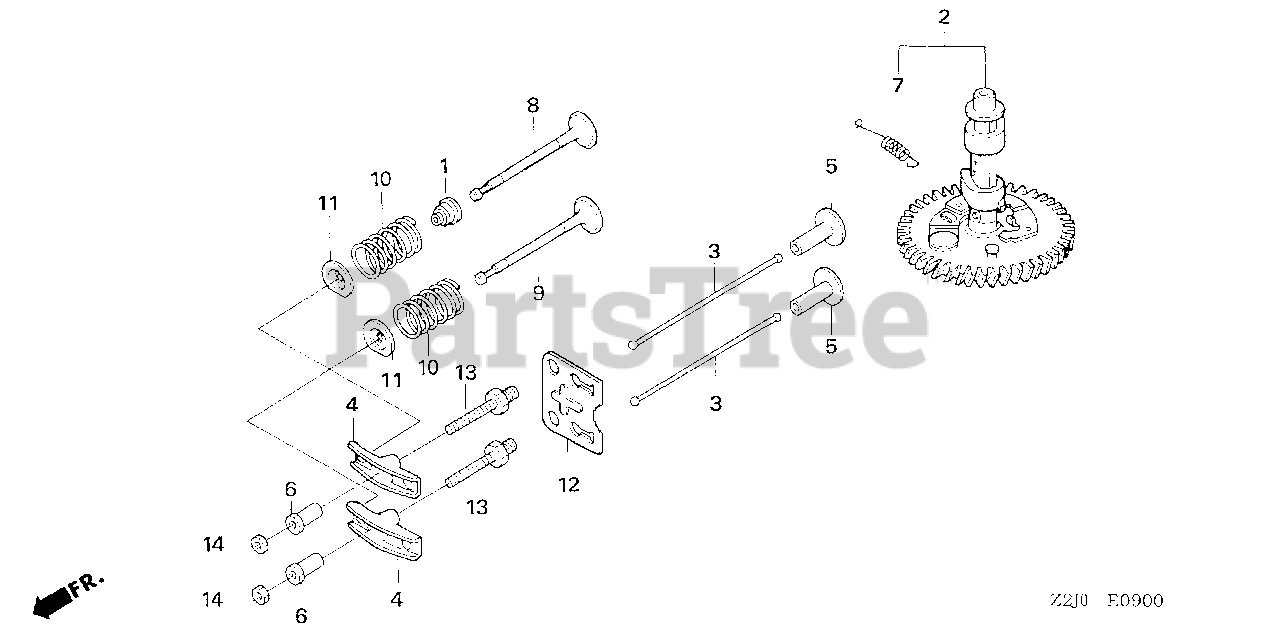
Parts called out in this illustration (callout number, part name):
1	SEAL, VALVE STEM
2	CAMSHAFT ASSY.
3	ROD, PUSH
4	ARM, VALVE ROCKER
5	LIFTER, VALVE
6	PIVOT, ROCKER ARM
7	SPRING, WEIGHT RETURN
8	VALVE, IN.
9	VALVE, EX.
10	SPRING, VALVE
11	RETAINER, IN. VALVE SPRING
12	PLATE, PUSH ROD GUIDE
13	BOLT, PIVOT (8MM)
14	NUT, PIVOT ADJUSTING
